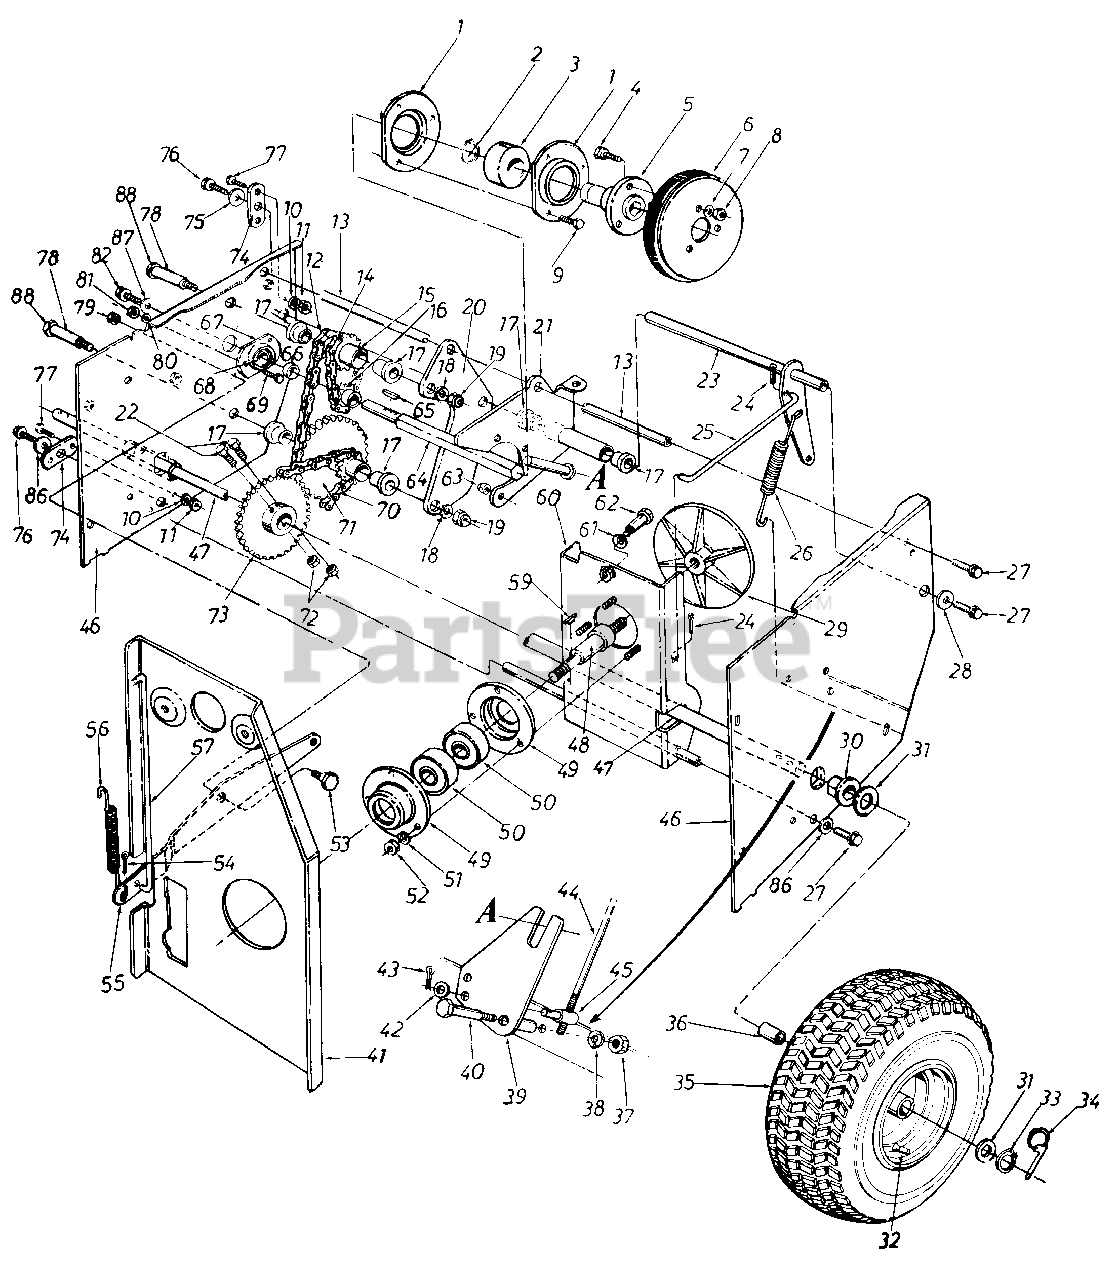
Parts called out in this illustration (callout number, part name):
1	Bearing Housing
2	Snap Ring-1.0" Dia.
3	Ball Brg. .25MM x 52MM x 15MM Thk.
4	Hex Sems Bolt 5/16-18 x .75" Lg. *
5	Friction Wheel Adapter
6	Friction Wheel Ass'y.
7	L-Wash. 5116" I.D.*
8	Hex Nut 5/16-18 Thd.*
9	Hex Bolt 1/4-28 x .62" Lg.*
10	L-Wash. 1/4" I.D.*
11	Hex Nut 1/4-20 Thd.*
12	#41 Chain-1/2" Pitch x 43 Links
13	Sliding Support Axle
14	#41 Chain-1/2" Pitch x 19 Links
15	9 and 14 Teeth Sprocket Hub Ass'y.
16	8 Teeth Sprocket
17	Flange Bearing .63" I.D.
18	L-Wash. 3/8" I.D.-H.D.
19	Hex L-Jam Nut 3/8-24 Thd.
22	Hex Bolt 5/16-24 x 1.75" Lg.
23	Drive Clutch Brkt. Ass'y.
24	Inter. Cot. Pin 5/16" Dia.*
25	Drive Clutch Rod .31" Dia. x 7.38" Lg.
26	Extension Spring 4.31" Lg.
27	Hex L-Bolt 5/16-18 x .62"
28	Fl-Wash. .345" I.D. x .75" O.D.
29	Aluminum Drive Plate
30	Flange Brg. w/Flats
31	Thrust Washer 1.03" I.D.
32	Tubeless Air Valve
33	Snap Ring 1.0" Shaft
35	Wheel Ass'y. Comp. 16 x 4.8
36	Bearing 1.0" I.D.
37	Hex Jam Nut 3/8-16 Thd.
38	L-Wash. 3/8" I.D.*
41	Engine Brkt. Ass'y.
42	Fl-Wash. .344" I.D. x .62" O.D.
43	Cotter Pin 3/32" Dia. x .75" Lg.
44	Shifting Rod
45	Adjustment Ferrule
46	Frame Ass'y.
47	Free Wheeling Axle
48	Drive Plate Spindle
49	Bearing Housing
50	Ball Brg. .787" I.D. x 1.85" O.D.
51	L-Wash. 5/16" I.D.
52	Hex Nut 5/16-18 Thd.*
53	Shld. Bolt .625" Dia. x .170" Lg.
54	Inter. Cotter Pin 5/16" Dia.
55	Auger Clutch Brkt.
56	Extension Spring .38" O.D. x 3.18" Lg.
57	Auger Clutch Rod .31" Dia. x 10.62" Lg.
59	#61 Hi-Pro Key 3/16" x 5/8" Dia.
62	Shld. Bolt
63	Hex Ins. Jam Nut 1/4-28 Thd.
65	#9 Hi-Pro Key 3/32" x 5/8" Dia.
66	Spacer .51" I.D. x .69" O.D.
67	Bearing Housing
68	Ball Bearing
69	Hex Bolt 1/4-20 x .62" Lg.*
70	#420 Chain 50n Pitch x 37 Links
71	9 and 32 Teeth Sprocket Hub Ass'y.
72	Hex L-Nut 5/16-24 Thd.
73	28 Teeth Sprocket Hub Ass'y.
74	Pivot Axle Brkt.
75	Fl-Wash. .345" I.D. x .75"
76	Hex L-Bolt 5/16-18 x .62"
77	Hex Bolt 1/4-20 x .62" Lg.*
78	Sprocket Hub Tubing 1.88"
79	Hex Cent. L-Nut 3/8-16 Thd.
80	L-Wash. 1/4" I.D.
81	Hex Nut 1/4-20 Thd.*
82	Hex L-Bolt 5/16-18 X .62"
86	Fl-Wash. .344" I.D. x .875"
87	Bell-Wash. .345" I.D. x .88"
88	Hex Bolt 3/8-24 X 2.75" Lg.
